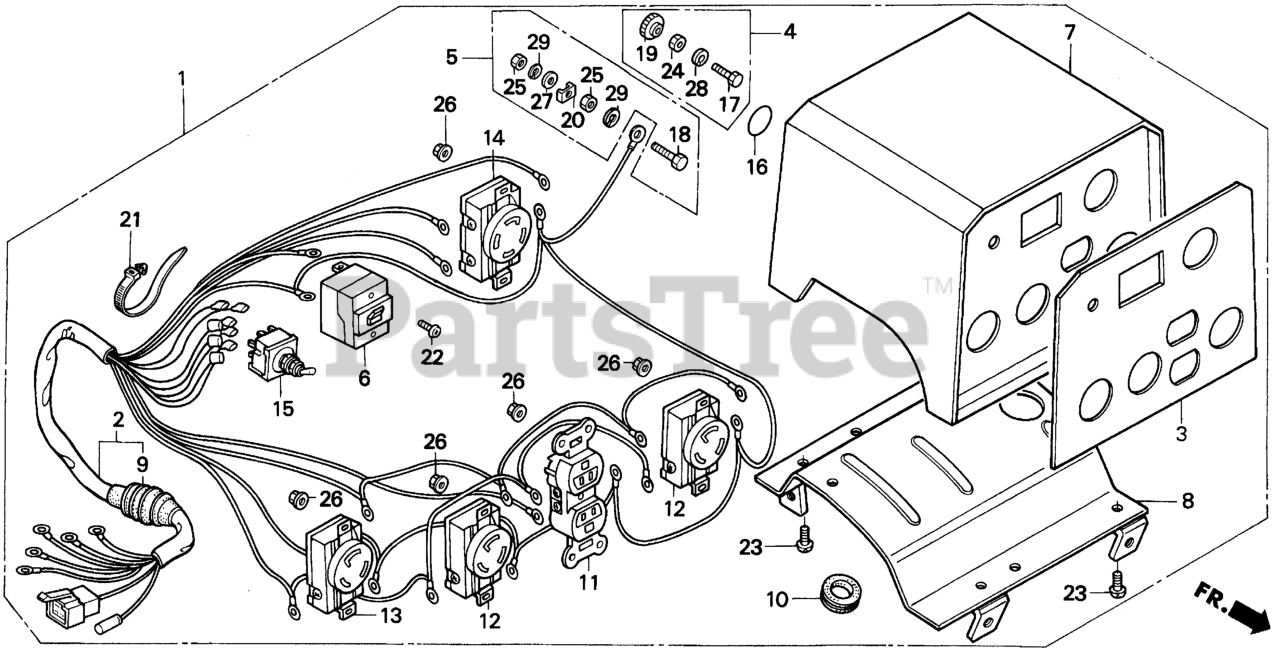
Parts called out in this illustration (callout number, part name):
1	BOX ASSY., CONTROL *R8* (EG-A) (BRIGHT RED)
1	BOX ASSY., CONTROL *R8* (BRIGHT RED)
2	WIRE HARNESS ASSY. (EG-A)
2	WIRE HARNESS ASSY. (EG-A) (NOT AVAILABLE)
3	PLATE, CONTROL INDICATOR (EG-A) (NOT AVAILABLE)
4	TERMINAL SET, GROUND
5	TERMINAL SET, GROUND
6	BREAKER, CIRCUIT (19A)
7	BOX, CONTROL *R280* (POWER RED)
8	PLATE (LOWER) *NH105* (MAT BLACK)
9	GROMMET, A.C. WIRE
10	GROMMET, MAIN WIRE
11	RECEPTACLE (20A/125V) (MATSUSHITA)
12	RECEPTACLE (20A/125V) (NOT AVAILABLE)
13	RECEPTACLE (30A/125V)
13	RECEPTACLE (3-PRONG) (30A/125V)
14	RECEPTACLE (4-PRONG) (30A/125-250V)
14	RECEPTACLE (30A/125-250V)
15	SWITCH ASSY., VOLT CHANGE
16	MARK, GROUND
17	BOLT, HEX. (6X22)
18	BOLT, HEX. (6X28)
19	NUT, SPECIAL (6MM)
20	RETAINER (6MM)
21	TIE, CABLE (NATURAL 225X5.0)
22	SCREW, PAN (4X6)
23	SCREW, PAN (6X10)
24	NUT, HEX. (6MM)
25	NUT, HEX. (6MM)
26	NUT, FLANGE (4MM)
27	WASHER, PLAIN (6MM)
28	WASHER, SPRING (6MM)
29	WASHER, SPRING (6MM)
